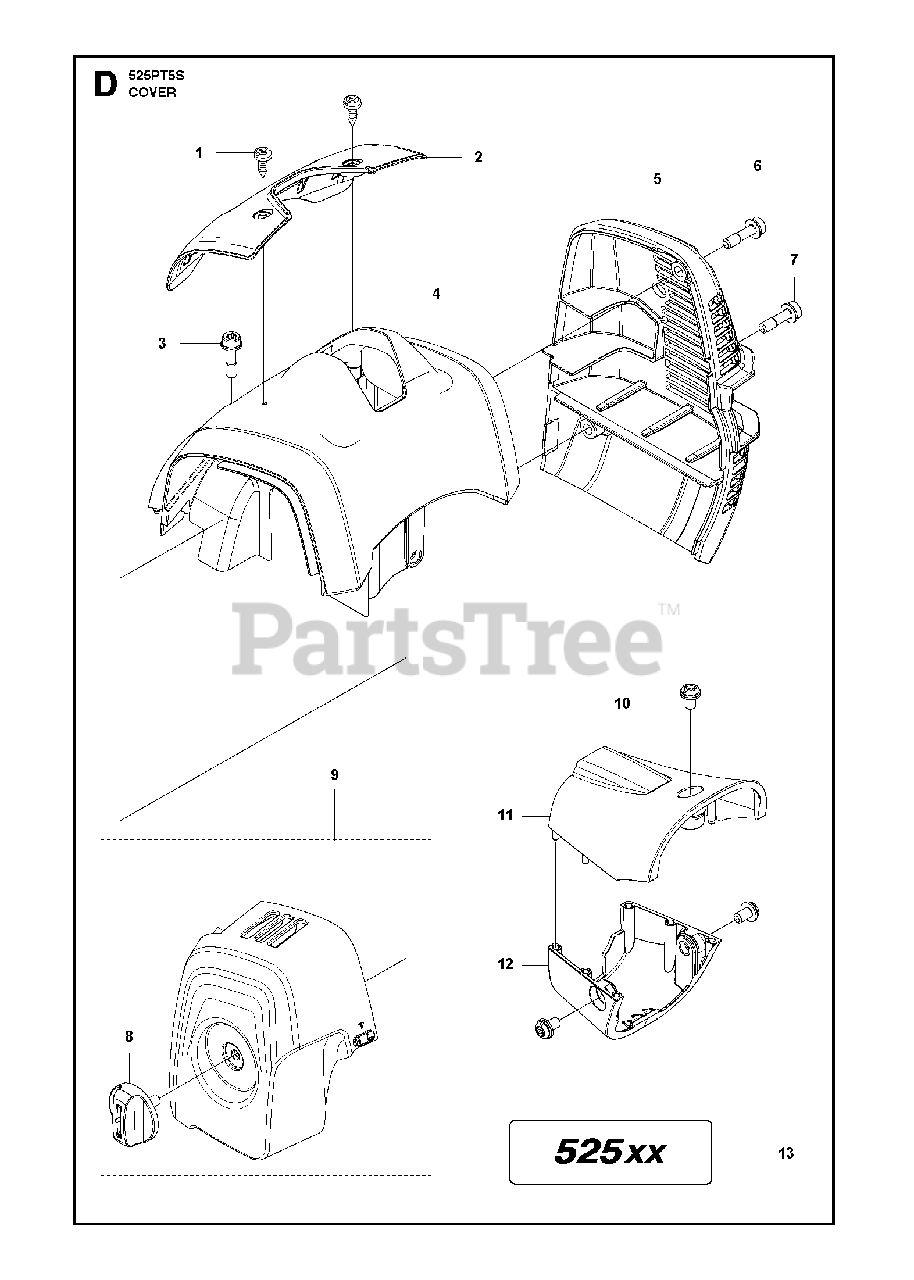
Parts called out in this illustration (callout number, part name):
2	ARM PROTECTION
3	BOLT
4	CYLINDER COVER ASSY
5	MUFFLER GUARD
6	BOLT
7	BOLT
8	KNOB CLEANER COLOR:GREY
9	FILTER COVER ASSY
11	COVER CLUTCH HOUSING,UPPER
11	COVER CLUTCH HOUSING UPPER
12	COVER CLUTCH HOUSING,LOWER
12	COVER CLUTCH HOUSING LOWER
13	DECAL NAME 525LS
